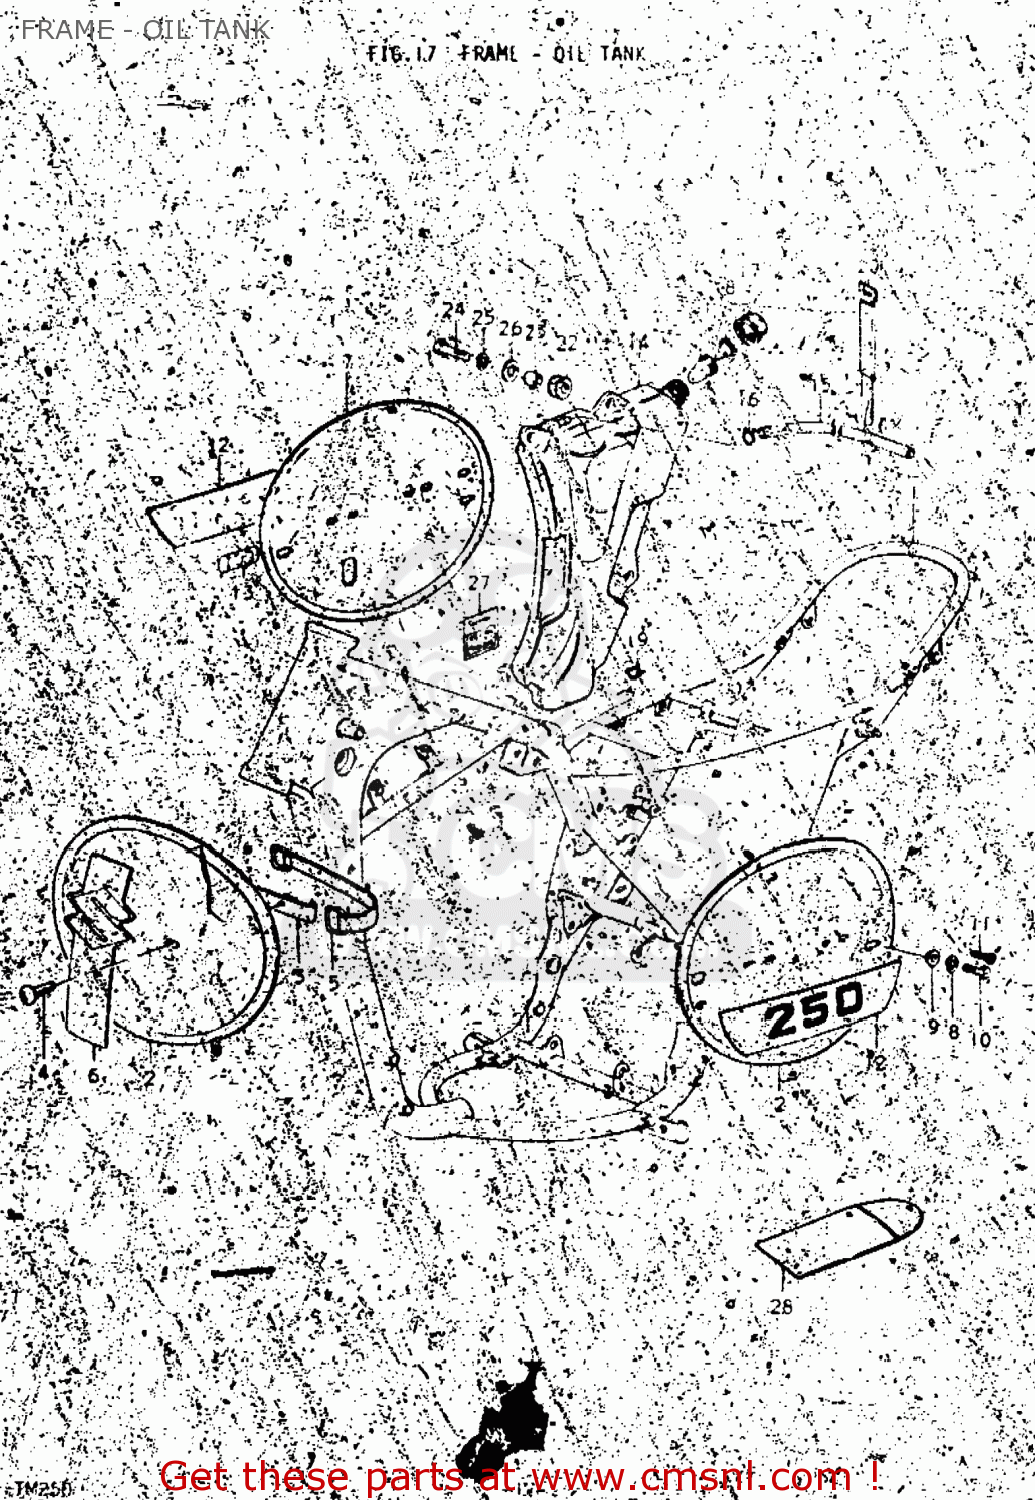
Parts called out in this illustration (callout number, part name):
1	FRAME
2	PLATE SET,FRONT
4	SCREW 6X12
5	BAND
6	EMBLEM,FRONT NUMBER PLATE
7	PLATE,NUMBER,FRONT
8	LOCK WASHER
9	WASHER
10	BOLT
11	SCREW 6X12
12	TAPE,FRAME COVER
13	EMBLEM,CCIS
14	TANK,OIL
15	HOSE
16	CLIP
17	CAP, OIL TANK
18	GASKET,OIL TANK (NAS)
19	CLIP
20	CLAMP
21	GASKET,OIL TANK CAP
22	CUSHION
23	SPACER (6.8X10X10)
24	BOLT
25	LOCK WASHER
26	WASHER (6.5X20X1.2)
27	LABEL
